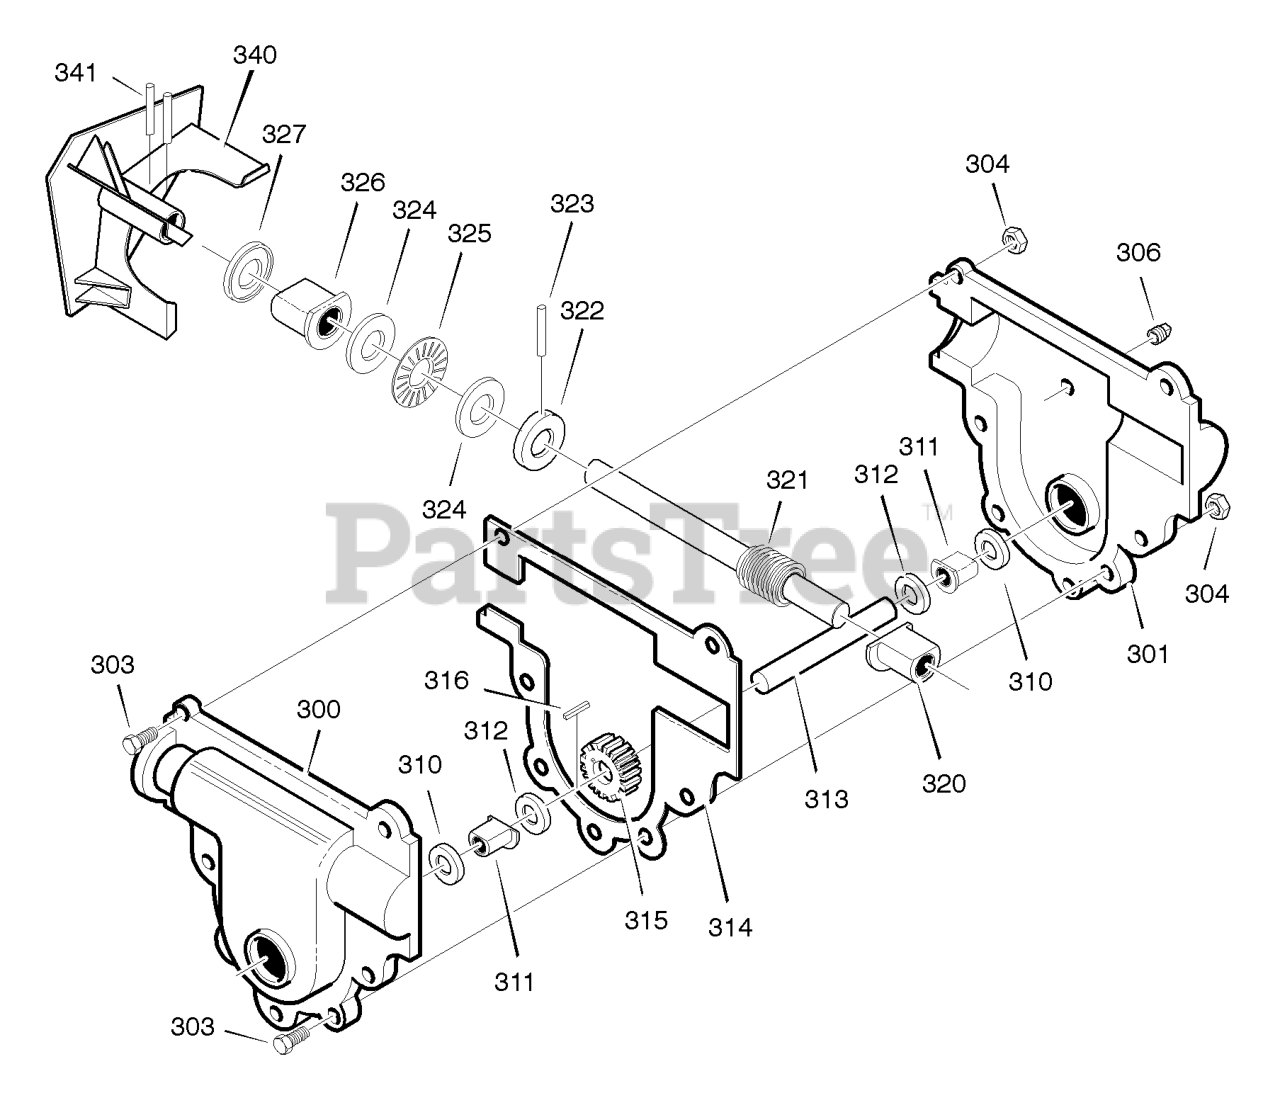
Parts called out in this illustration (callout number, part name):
300	CASE, GEAR, RH
301	CASE, GEAR, LH
306	SCREW
310	SEAL, OIL
311	BEARING, FL
312	WASHER, FLAT
313	SHAFT, OUTPUT
315	GEAR, WORM
316	KEY, WOODRUFF
320	BRNG, FL
321	SHAFT, INPUT
322	COLLAR, THRUST
323	PIN, SPRING
324	WASHER, FLAT
325	BRNG, ROLL
326	BRNG, FL
327	SEAL, OIL
340	IMPELLER ASSEMBLY
341	PIN, SPRING
